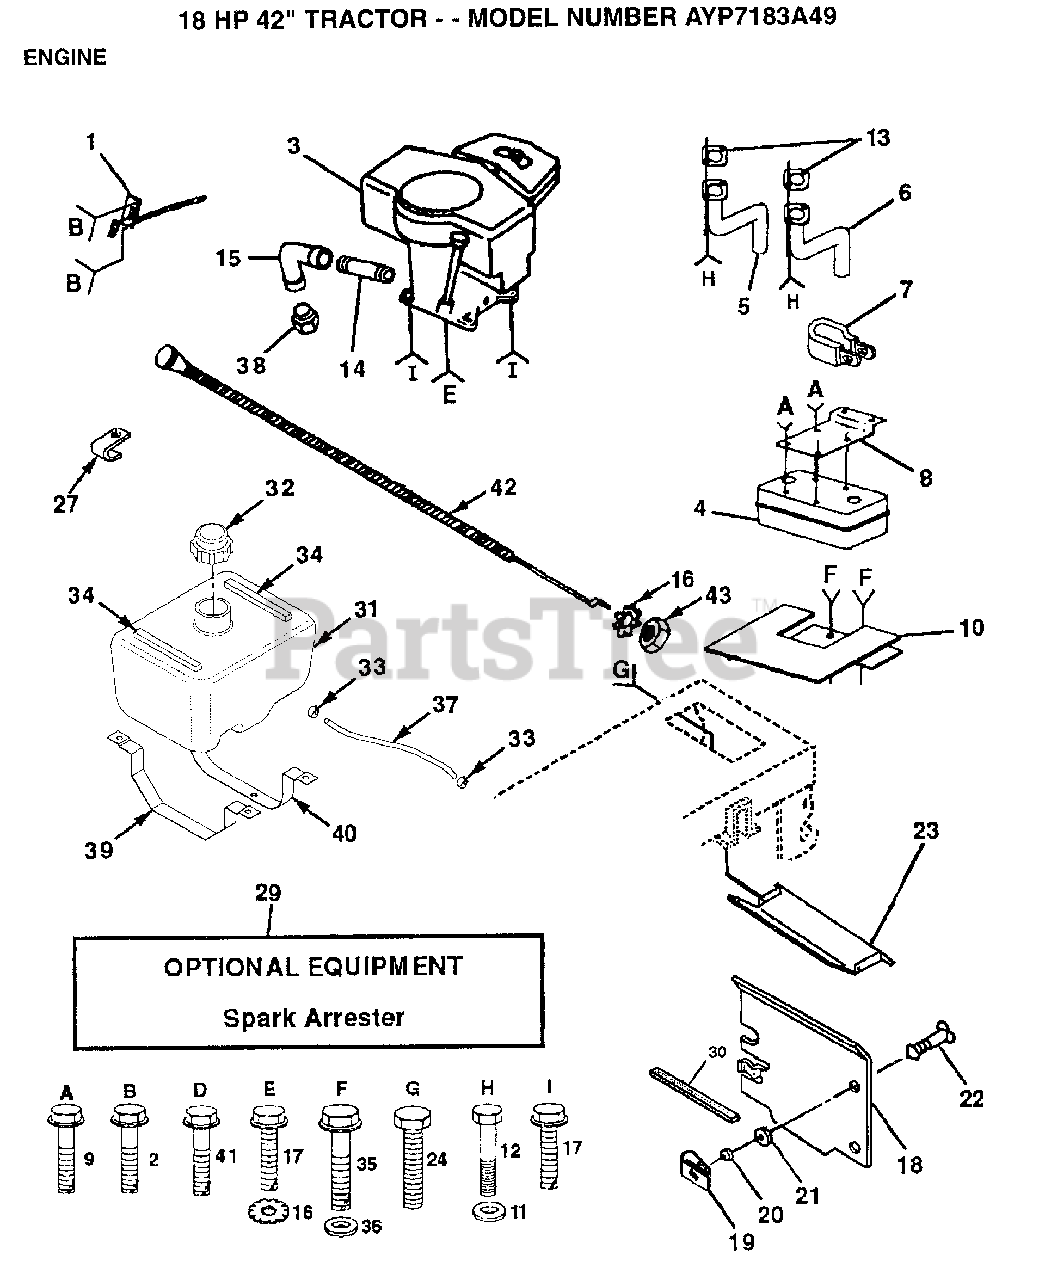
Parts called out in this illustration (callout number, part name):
2	SCREW LT
5	EXHAUST ASM LH
7	CLAMP.TUBE.DBL.EN
8	BRACKET MUFFLER
9	SCREW ST
14	PIPE NIPPLE LT
15	ELBOW
16	LOCKWASHER
17	SCREW LT
18	SHIELD HEAT
19	RECEPTACLE LT
20	RETAINER LT
21	WASHER
22	STUD.1/4.TURN
23	HEAT SHIELD
24	SCREW
27	"CLIP,INSULATOR"
31	TANK FUEL 1.9 NAT
32	CAP ASM FUEL
33	HOSE CLAMP
34	"STRIP,FORM"
35	SCREW
36	WASHER
37	FUEL LINE T
39	STRAP TANK FUEL
40	STRAP TANK FRONT
41	SCREW
42	CONTROL.CHK.26.38
